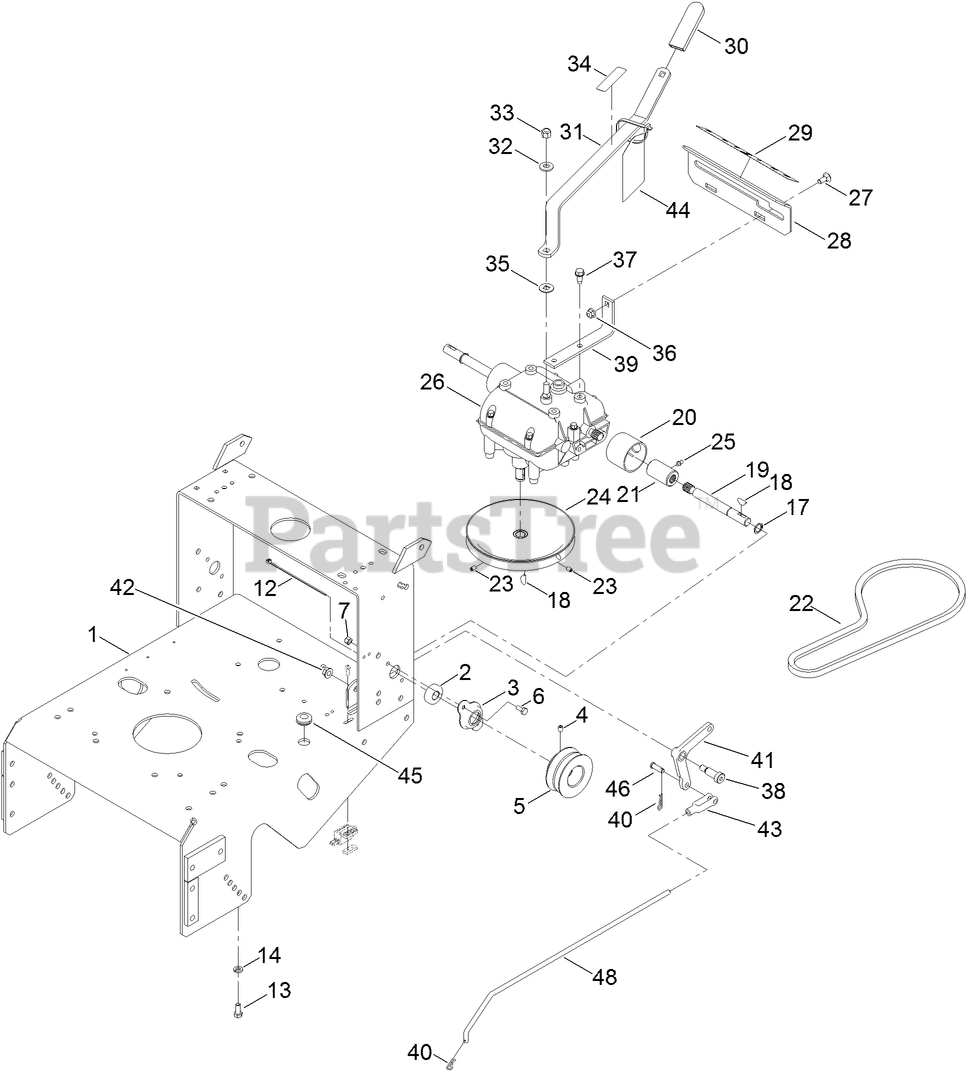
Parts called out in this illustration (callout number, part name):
1	FRAME-GEAR
2	BEARING-SHAFT
3	FLANGE-OUTPUT
4	SETSCREW
5	SHEAVE-TRANSMISSION
6	SCREW-HH
7	NUT-LOCK, NI
12	TIE-CABLE
13	SCREW-HH
14	WASHER-LOCK
17	RING-RETAINING
18	KEY-WOODRUFF
19	SHAFT-TRANSMISSION
20	GUARD-COUPLER
21	COUPLER
22	V-BELT
23	SCREW-HSH
24	SHEAVE-TRANSMISSION
25	FITTING-GREASE
26	TRANSMISSION-5 SPEED
27	BOLT-CARR
28	PLATE-SHIFT
29	DECAL-SPEED, GROUND
30	GRIP-LEVER
31	LEVER-SHIFT
32	WASHER-BELLEVILLE
33	NUT-LOCK
34	DECAL-CAUTION, GEARBOX
35	WASHER
36	NUT-HF, NI
37	SCREW-THD ROLL, HWH
38	BOLT-SHOULDER
39	BRACKET-PLATE, SHIFT
40	PIN-COTTER
41	BELLCRANK
42	NUT-HHF, WHIZ
43	YOKE-ADJUSTABLE
44	HANG TAG-GEARBOX
45	GROMMET
46	PIN-CLEVIS
48	ARM-ASSIST, LINKAGE
